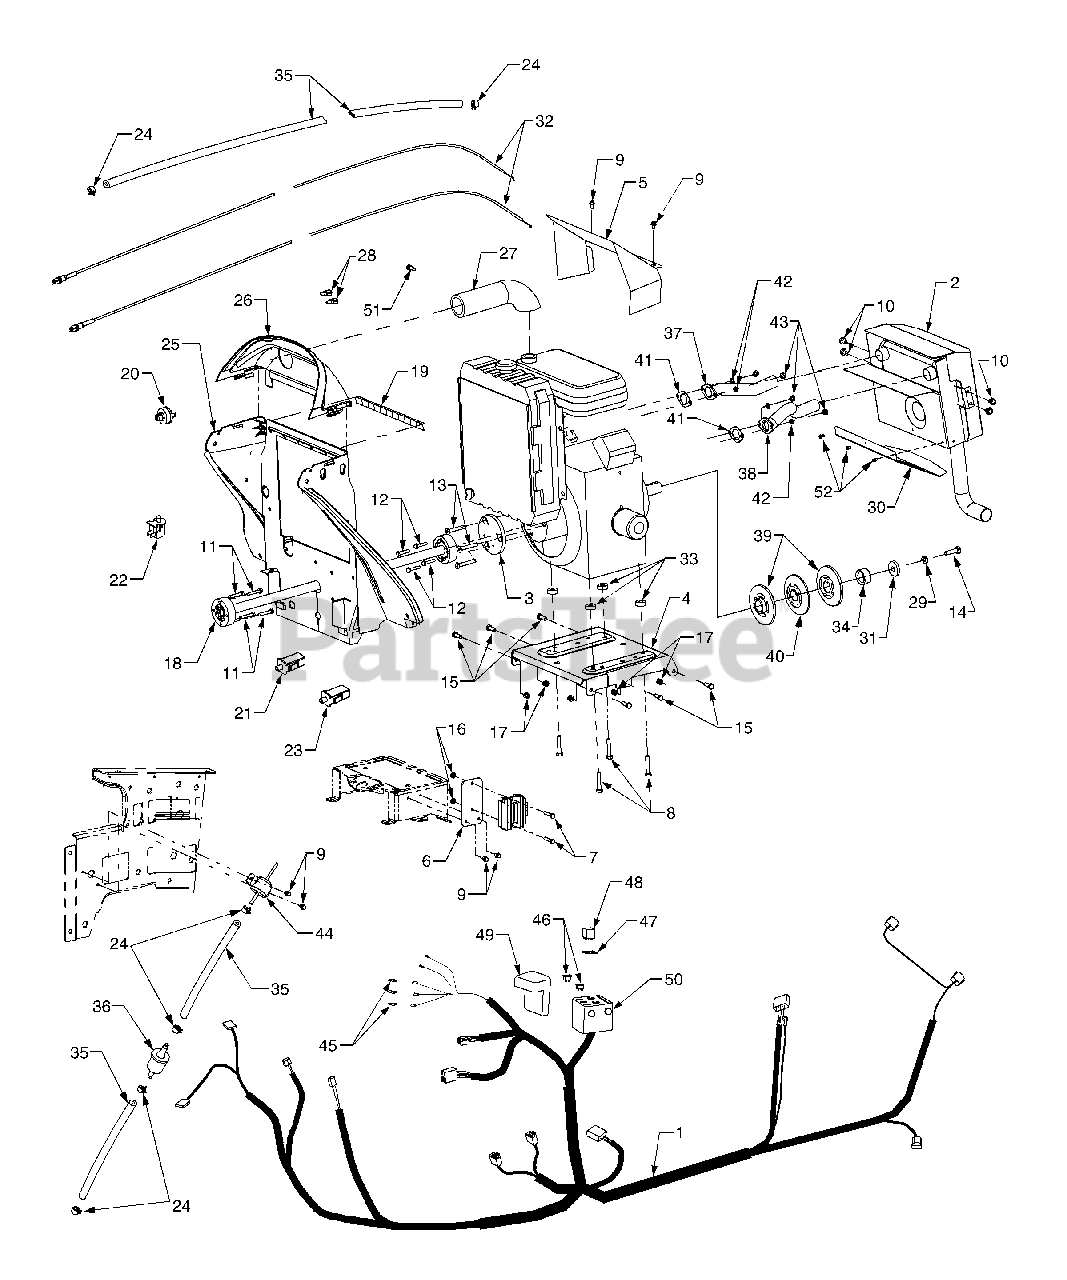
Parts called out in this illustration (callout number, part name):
1	Harness, Wire
2	Muffler Assembly
3	Plate, Coupling Adapter
4	Plate, Engine Mounting
5	Shield, Muffler Heat
6	Plate, Regulator Mounting
7	Screw, Hex Cap, 1/4-20 x 1.25 GR5
8	Screw, Hex Cap, M8-1.25 x 25 GR8.8
9	Screw, Hex Wash. Hd. Tapp, 1/4-20 x .5
10	Screw, Hex Wash. Hd. Tapp, 5/16-18 x .5
11	Screw, Hex Cap, Lock 1/4-20 x 1.25 GR5
12	Screw, Hex Cap, Lock 1/4-20 x 1.25 GR5
13	Screw, Countersink Machine, M8-1.25 x 55MM
14	Screw, Hex Cap, M10-1.5 x 35MM
15	Screw, Hex Cap, 5/16-18 x .875 GR5
16	Nut, Hex Sems, 1/4-20
17	Nut, Hex Insert Lock, 5/16-18
18	Shaft, Drive, 27.75 Long
19	Foam Tape 46" Lg
20	Switch, Key,
21	Switch, Plunger
22	Switch, Snap Mount
23	Switch, Plunger
24	Clamp, Hose
25	Baffle, Lower Air
26	Baffle, Upper Air
27	Hose, Intake
28	Clip, Fuel Line Retainer
29	Washer, Lock, 7/16
30	Shield, Lower Exhaust
31	Washer, Flat, .417 x 1.5 x .225
32	Cable, Choke and Throttle Control
33	Spacer, Engine, 1.0 O.D, x .34 Lg
34	Spacer, Crankshaft
35	Fuel Line, 12 inches
35	Fuel Line, 68" Lg
36	Filter, Fuel
37	Pipe, Exhaust
38	Pipe, Exhaust
39	Pulley Half
40	Pulley, Center
41	Gasket, Exhaust
42	Washer, Lock, 6MM
43	Nut, Hex, 6MM
45	Bulb, Indicator
46	Fuse, 25 Amp
47	Gasket, Silicone
48	Relay
49	Cover, Fuse Box
50	Box, Fuse
51	Screw, Engine Ground, M8-1.25 x 16
52	Screw, Hex Wash. Hd. Tapp. #12-24 x .375
